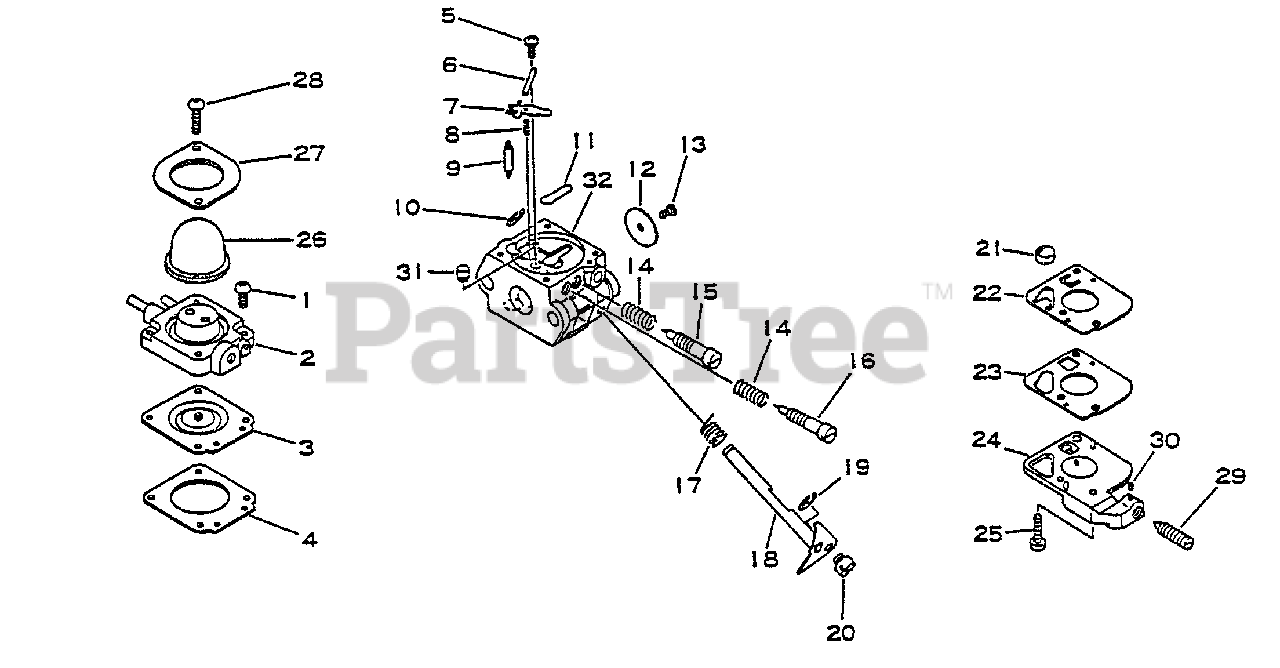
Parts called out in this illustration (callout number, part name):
2	BODY ASSY, PURGE
3	DIAPHRAGM
4	GASKET, DIAPHRAGM
5	SCREW
6	PIN, METERING LEVER
7	LEVER, METERING
8	SPRING
9	VALVE, NEEDLE
11	PLUG, WELCH
12	VALVE, THROTTLE
14	SPRING, NEEDLE
15	NEEDLE, IDLE
16	NEEDLE, HIGH SPEED
17	SPRING, THROTTLE RETURN
18	SHAFT, THROTTLE
21	STRAINER
22	DIAPHRAGM, PUMP
23	GASKET, PUMP
24	COVER, PUMP
26	BULB, PURGE
27	RETAINER
29	SCREW, IDLE ADJUST
30	PIECE, FRICTION
31	NOZZLE, CHECK VALVE
